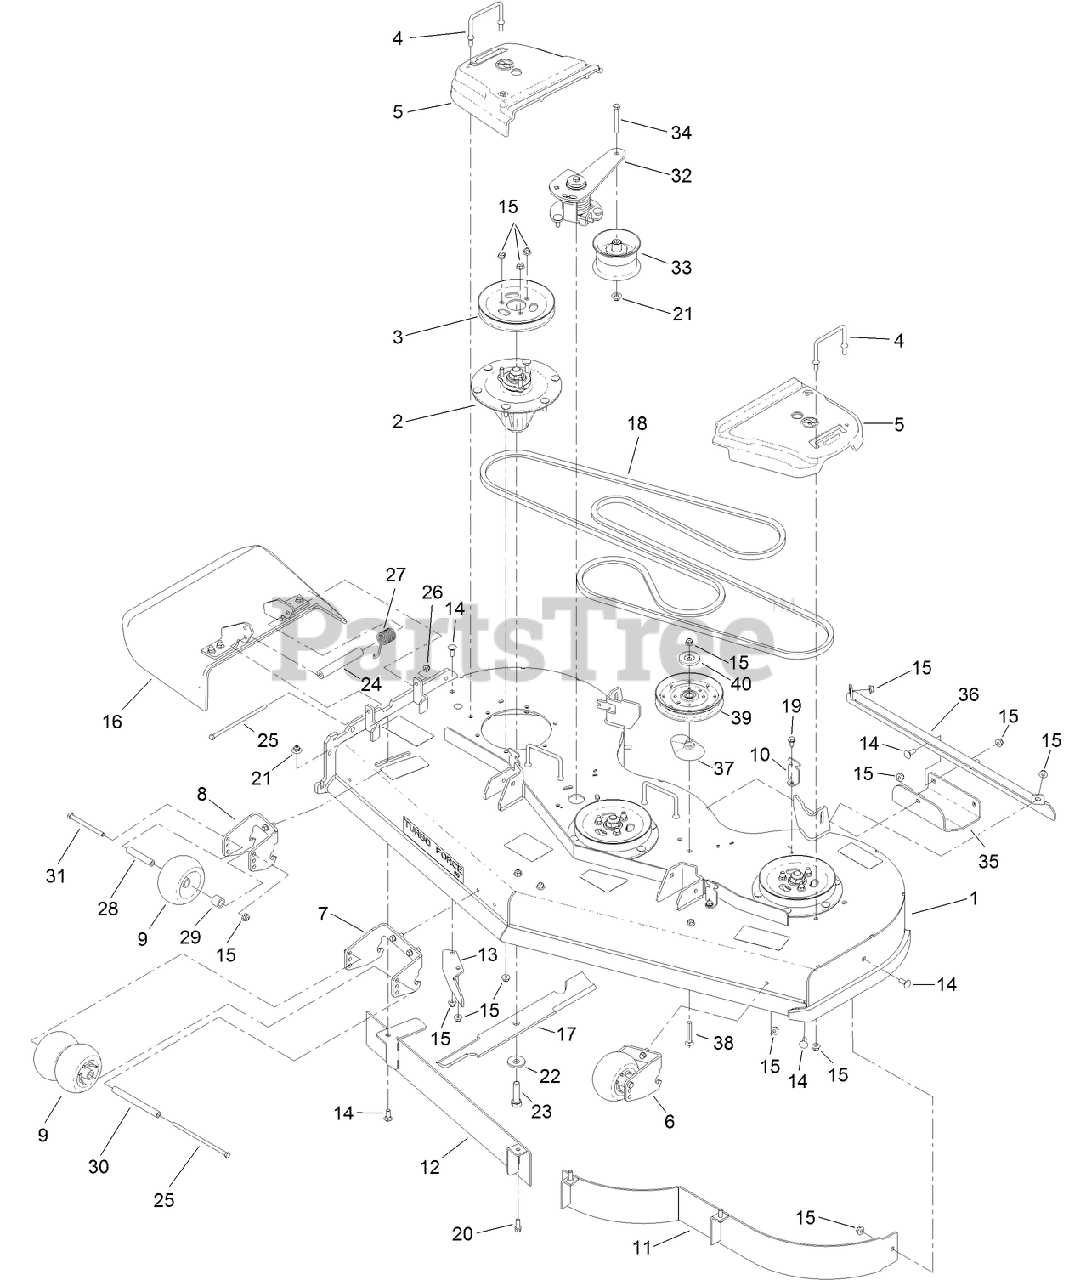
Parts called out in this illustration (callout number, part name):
1	DECK ASM
2	SPINDLE ASM
3	PULLEY
4	WIREFORM-COVER
5	COVER-BELT, LH
6	BRACKET-WHEEL, LH
7	BRACKET-WHEEL, CENTER
8	BRACKET-WHEEL, RH
9	ROLLER-SCALP, ANTI
10	BRACKET-COVER
11	BAFFLE ASM
12	BAFFLE ASM
13	BAFFLE-DISCHARGE
14	BOLT-CARR
15	NUT-HF, NI
16	DEFLECTOR ASM
17	BLADE-HI FLOW
18	BELT-V
19	SCREW-HWHTF
20	SCREW-HWH
21	NUT-FLANGE, NI
22	Washer-Blade Bolt, Heavy
23	SCREW-BLADE
24	SPACER
25	SCREW-HH
26	NUT-HF, NI
27	SPRING-TORSION
28	TUBE-SPANNER
29	TUBE-SPACER
30	SPACER-WHEEL
31	SCREW-HH
32	TORSION IDLER ASM
33	PULLEY-IDLER
34	SCREW-HH
36	BRACKET-SKID
37	SPACER-PULLEY
38	SCREW-CARR
39	IDLER-PULLEY, FLAT
40	SHIELD-DUST
